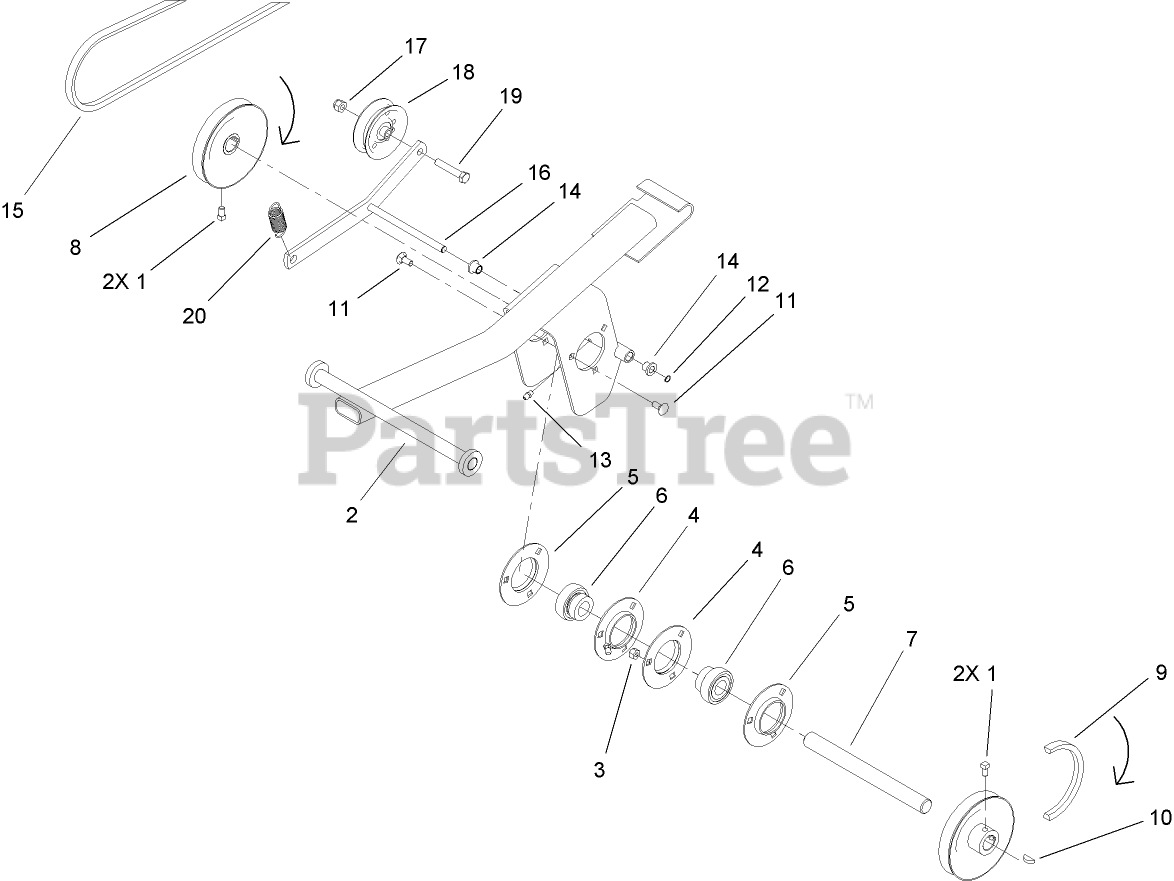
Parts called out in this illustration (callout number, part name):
1	SCREW-SQH
2	SUPPORT-JACKSHAFT
3	NUT-LOCK, NI
4	FLANGE-ZERK RELUBE
5	FLANGE
6	BEARING AND COLLAR
7	SHAFT-JACK
8	PULLEY-V
9	V-BELT, TRACTION
10	KEY-WOODRUFF
11	BOLT-CARR
12	RING-RETAINING
13	FITTING-GREASE
14	BUSHING-FLANGED
15	V-BELT
16	IDLER ASM
17	NUT-LOCK, NI
18	PULLEY-IDLER
19	SCREW-HH
20	SPRING-EXTENSION
